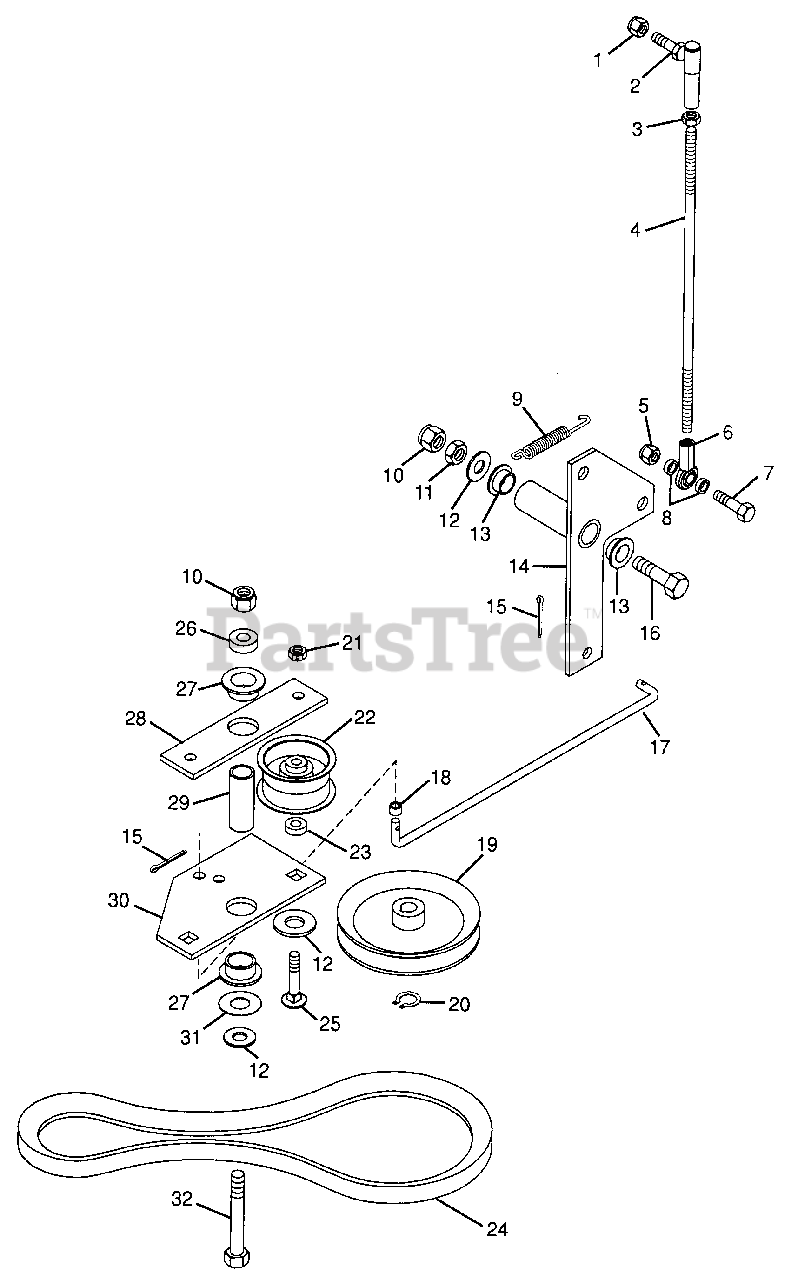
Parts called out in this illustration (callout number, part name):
1	Nut-Locking-Nylon .375-24 Grade 2
2	Joint, Steering Ball
3	Nut-Hex .375-24 Grade 2
4	Rod, Clutch Actuating
5	Nut-Locking-Nylon .375-16 Grade 2
6	Rod End, Spherical Bearing
7	Bolt-Hex .38-16 x 1.50 Grade 5
8	Bushing-Flange .383 x .50 x .165
9	Spring-Tension .095 x .500 x 5.5
10	Nut-Locking-Nylon .50-13 Grade 5
11	Nut .50-13
12	Washer-Flat-Steel .531 x 1.06 x .095
13	Bushing-Flange .515 x .750 x .745 x 1.00
14	Weldment, Clutch Arm
15	Pin-Cotter .09 x .75
16	Bolt-Hex .50-13 x 4.50
17	Rod, Traction Clutch
18	Bushing, Steel .380 x .495 x .437
19	Sheave, Transmission
20	Ring-Retaining-External .579 x .93
21	Nut-Locking-Center .625-10 Grade 2
22	Idler-Flat 2.468 x .38
23	Bushing .406 x .750 x .188
24	V-Belt A-Section
25	Bolt-Round Head Square Neck .38-16 x 1.75
26	Bushing, Steel .790 x 1.00 x .320
27	Bushing-Flange .762 x 1.0 x .580 x 1.48
28	Plate, Idler
29	Bushing, Steel .560 x .745 x 2.04
30	Plate, Idler
31	Bearing-Needle-Thrust .752 x 1.24 x .093
32	Bolt-Hex .50-13 x 3.00
